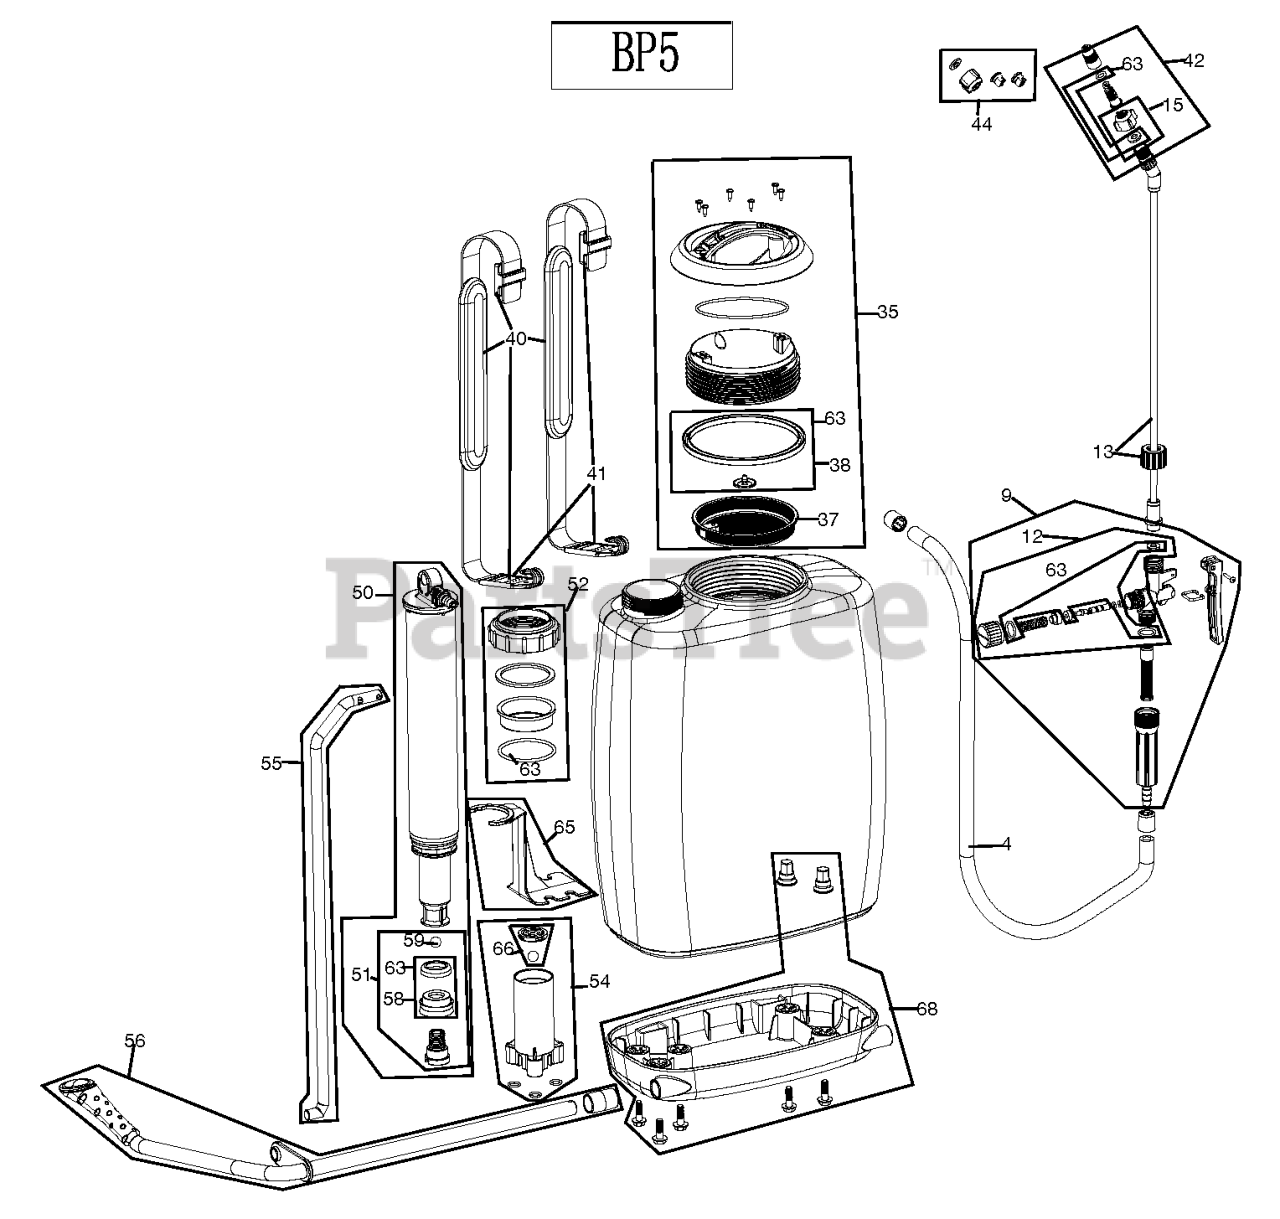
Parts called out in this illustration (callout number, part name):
4	HOSE AND 2 HOSE CLAMPS
9	COMP SPRAY PISTOL WBUILTNFILTE
12	SPINDLE SET
13	BRASS SPRAY WAND 20"
15	NOZZLE HOLDER
16	SILICONE GREASE
35	BACKPACK LID & SEAL W/HANDLE
40	SHOULDER STRAPS (SET OF 2)
41	BUCKLE & HOOK FOR STRAP
42	ADJ BRASS NOZZLE WITH HOLDER
44	PLASTIC SPRAY TIP SET (2-8004)
50	COMPLETE PUMP ASSEMBLY
51	PISTON HOLDER
52	HOLDER W/GUIDE, SEAL & ORING
54	COMPLETE CYLINDER
55	PUMP HANDLE W/ GRIP
56	PUMP LEVER W/ LOCKING PIN
57	LOCKING PIN-PUMP HANDLE (SML)
58	2-LIP PISTON CUP & PLASTIC CUP
59	STAINLESS STEEL BALL
63	SEAL SET BP5 BM46I
66	PLASTIC GRATE FOR CYLINDER
67	BASE ASSY BM46I
68	BASE ASSY COMP BP5
69	LID ORANGE W/LID & CARRY HNDL
